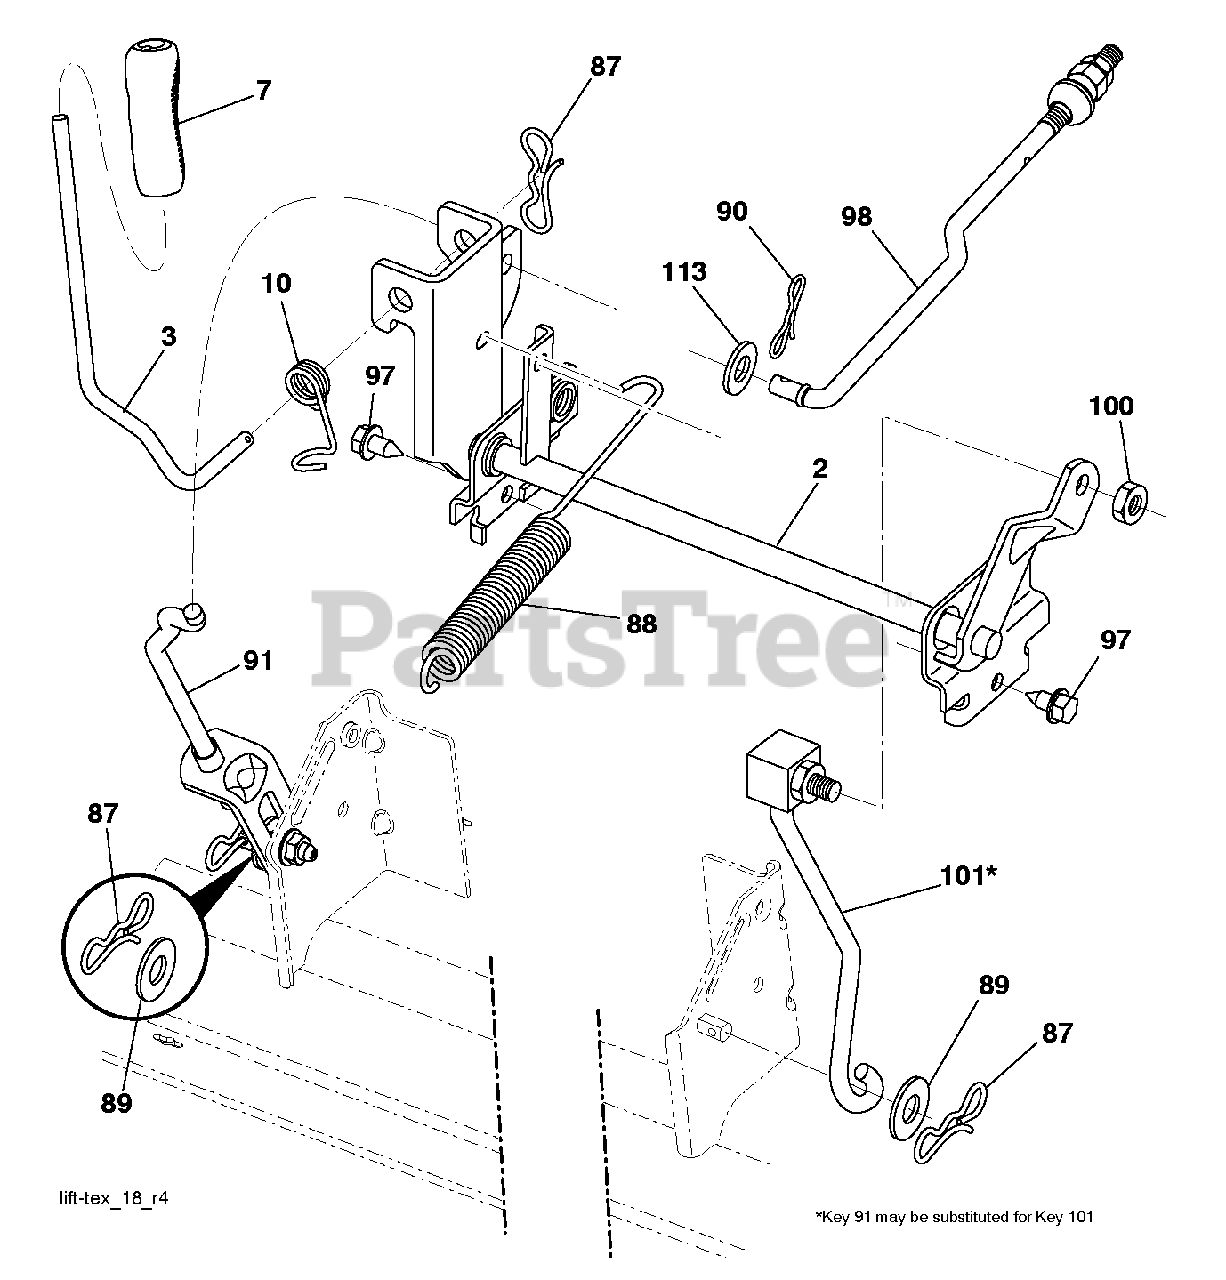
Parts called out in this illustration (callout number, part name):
2	SHAFT.ASM.CROSS.LIFT
3	LEVER.LIFT.HANDLE.LT
7	GRIP.HANDLE.LIFT.PVC.BLACK
10	SPRING.TORSION.LIFT.HANDLE
87	PIN.COTTER.7/16.BOW TI.
88	SPRING.LIFT.ASSIST
89	WASHER.CLEAR.ZINC
90	PIN.COTTER.5/16.BOW TI
91	LINK.ASM.LIFT.REAR
97	SCREW, 3/8-16X3/4
98	LINK.ASM.SUSP.FRONT.MWR.10.5
100	LOCKNUT
101	LINK.ASM.LIFT.FIXE.38/42/46"
